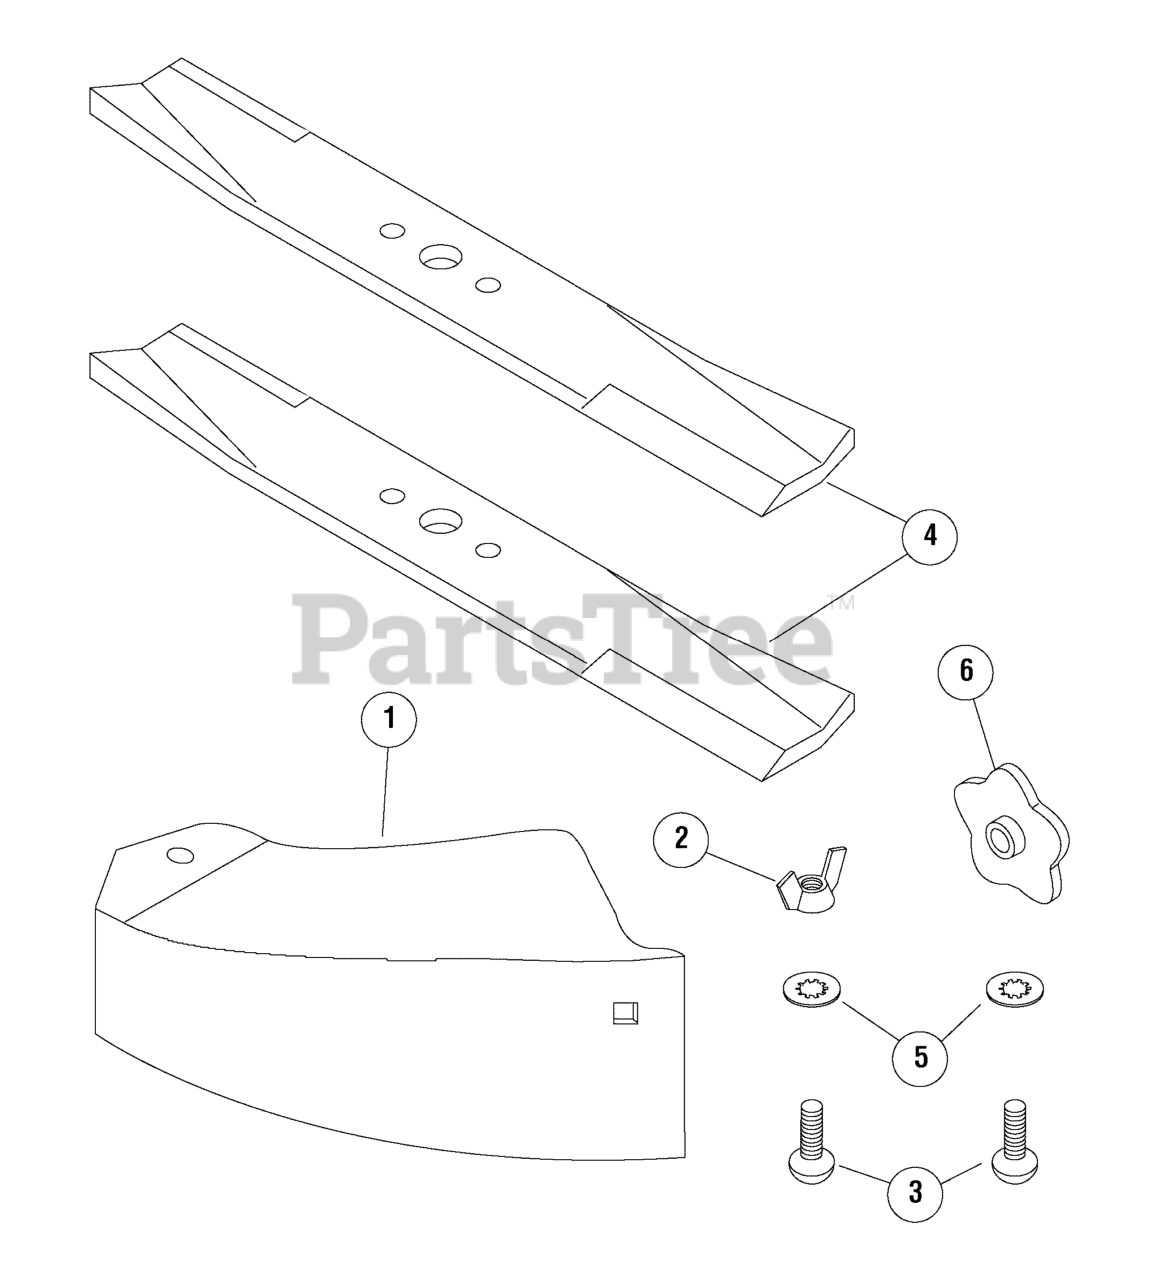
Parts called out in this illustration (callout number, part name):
1	COVER, Mulch
2	NUT, Wing, 5/16-18
3	BOLT, Carriage, 5/16-18 x 3/4
4	BLADE, 42" Mower Deck
5	NUT, Push, 5/16
6	KNOB, Plastic, 5/16-18
